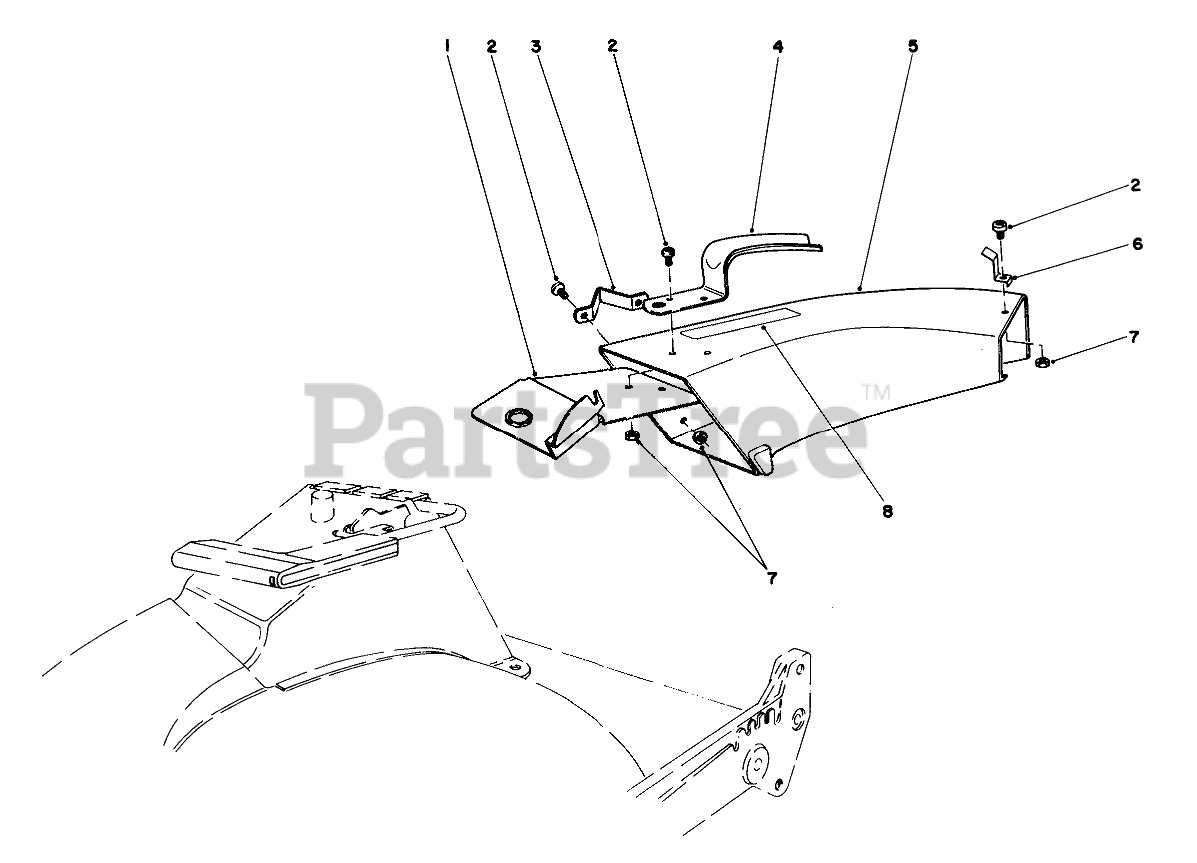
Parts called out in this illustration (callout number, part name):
1	Plate-Discharge Chut
2	RING-GRIP
3	SIDE BRACKET
4	CHUTE HANDLE
5	Chute-Discharge
7	NUT-LOCK, NI
8	DECAL CAUTION
